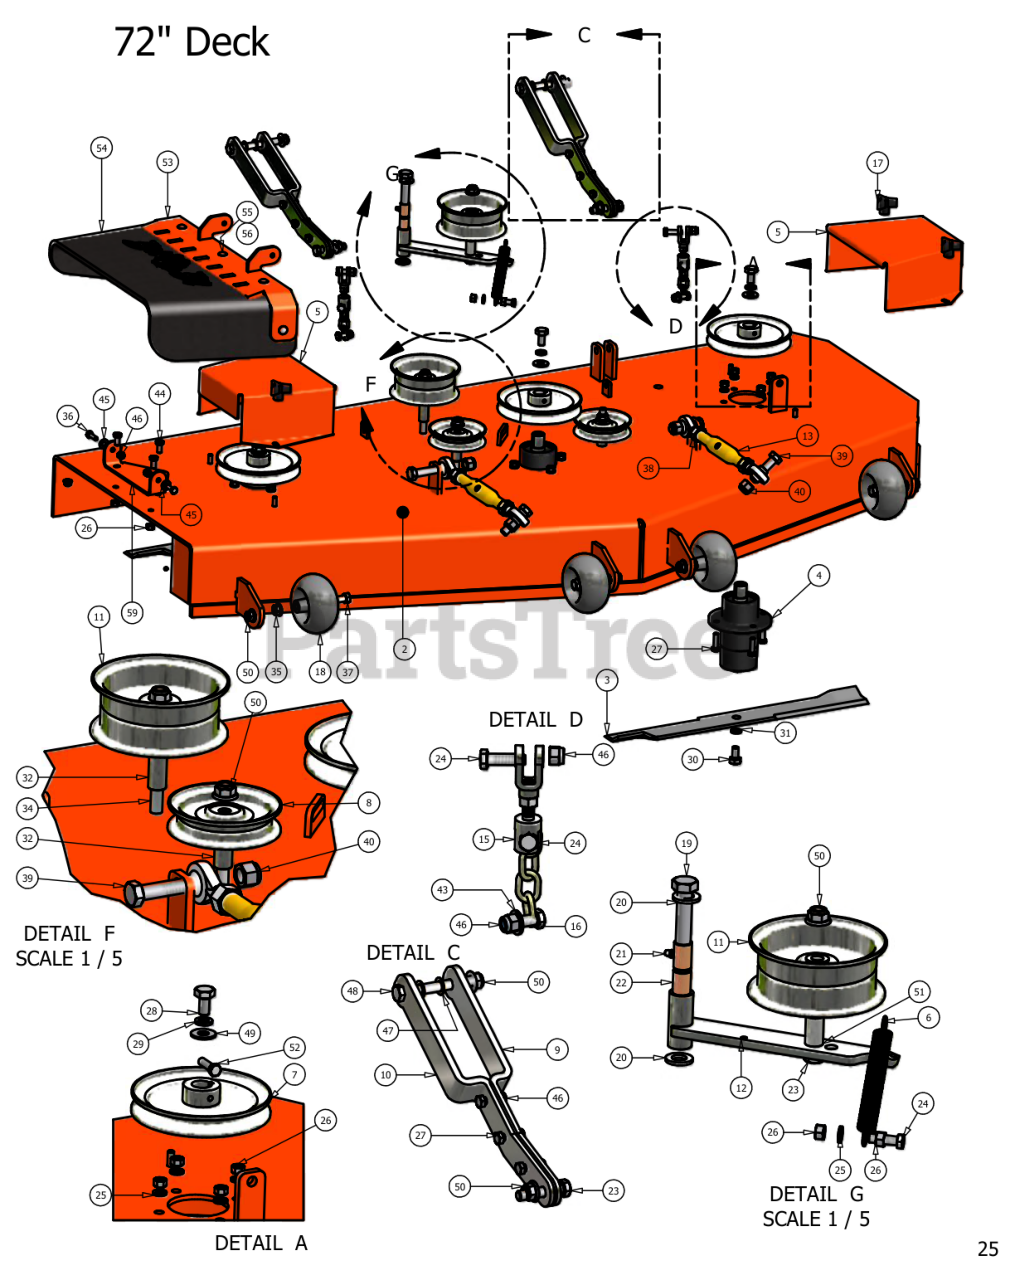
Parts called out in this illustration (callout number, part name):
1	72" Deck Belt-B189
3	72" Fusion Blade
5	Pulley Guard
6	Deck Idler Spring
7	7" Deck Pulley
8	4 3/4" Idler Pulley
9	Deck Support Arm (Right)
10	Deck Support Arm (Left)
11	5 3/4" Flat Idler Pulley
12	Deck Idler Arm
13	Turnbuckle
14	Female Yoke
17	5/16" Knob
18	Anti-Scalp Rollers
19	5/8" x 4" Hex Bolt
20	.635 ID Plastic Washer
21	Grease Fitting (Drive-In Type)
22	5/8" ID x 1 1/8" Brass Bushing
23	1/2" x 2 1/2" Hex Bolt
24	3/8" x 1 1/4" Hex Bolt
25	3/8" Lock Washer
26	3/8" Hex Nut
27	3/8" x 1 1/4" Hex Bolt
28	1/2" x 1 1/2" Fine Thread Bolt
29	1/2" Lock Washer
30	5/8" x 1.5" Fine Threaded Bolt
31	5/8" Lock Washer
32	1 1/2" Pulley Spacer
33	1 3/4" Pulley Spacer
34	1/2" x 3 1/2" Bolt
35	1/2" Flange Nut
36	5/16" x 1" Hex Bolt
37	1/2" x 4" Bolt (Grade 8)
38	3/4" Left Handed Nut
39	5/8" x 2 1/2" Hex Bolt
40	5/8 Std NC Nylock Nut
41	3/8" Fine Threaded Jam Nut
43	3/8" Flat Washer
44	3/8" x 3/4" Hex Bolt
45	.360 ID Plastic Washer
46	5/16" Nylock Nut
47	1/2" Brass Washer
48	1/2" x 4 1/2" Bolt
49	1/2" Cupped Washer
50	1/2" Flange Lock Nut
51	1 1/4" Pulley Spacer
52	3/8" Hex Bolt
53	2007 Hanger Plate
54	Rubber Side Discharge
55	5/16" x 1 1/2" Carriage Bolt
56	5/16" Nylock Flange Nut
57	2007 Lower Hanger Plate
58	1/2" x 3" Bolt
59	2007 Lower Hanger Plate
